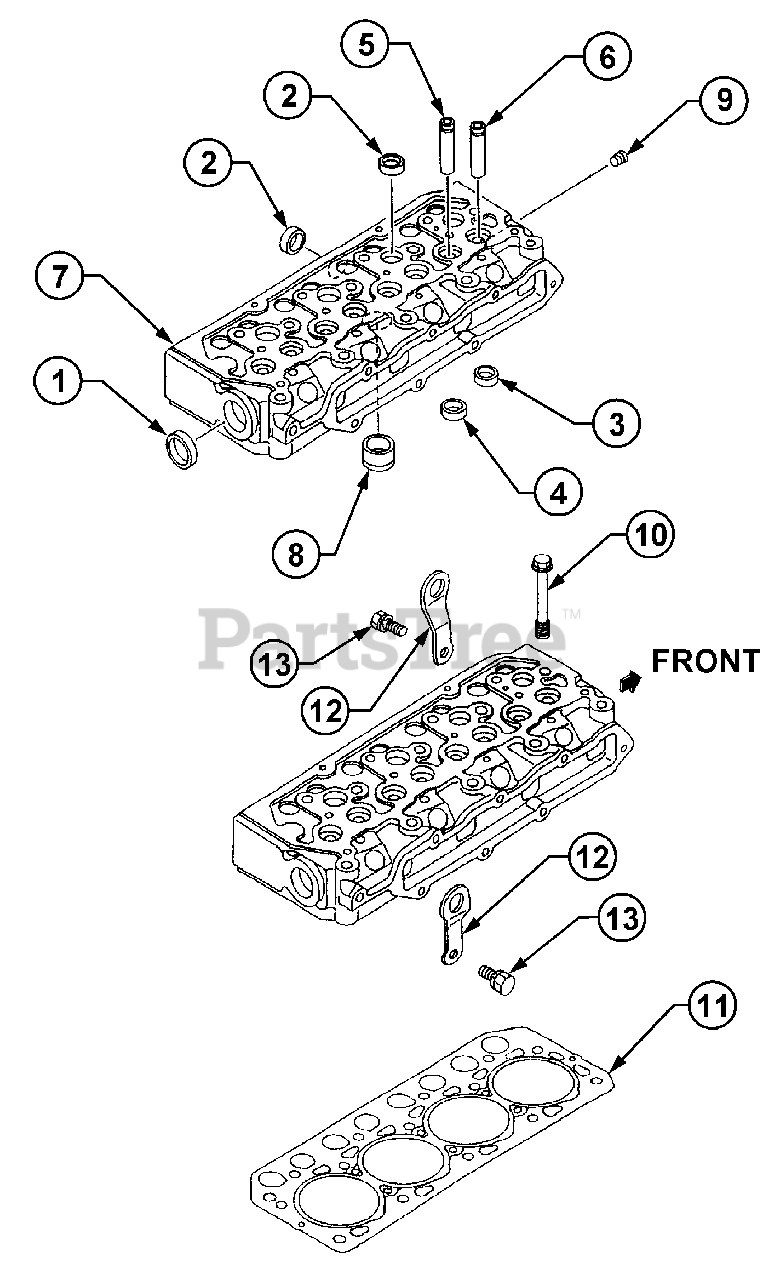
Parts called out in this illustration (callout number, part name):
1	Cap, Sealing
2	Cap, Sealing
3	Valve Seat In
4	Valve Seat Ex
5	Valve Guide Ex
6	Valve Guide In
7	Cylinder Head
8	Jet, Combustion
9	Plug, Taper
10	Bolt, Head
12	Hanger, Engine
13	Bolt, w/Washer
